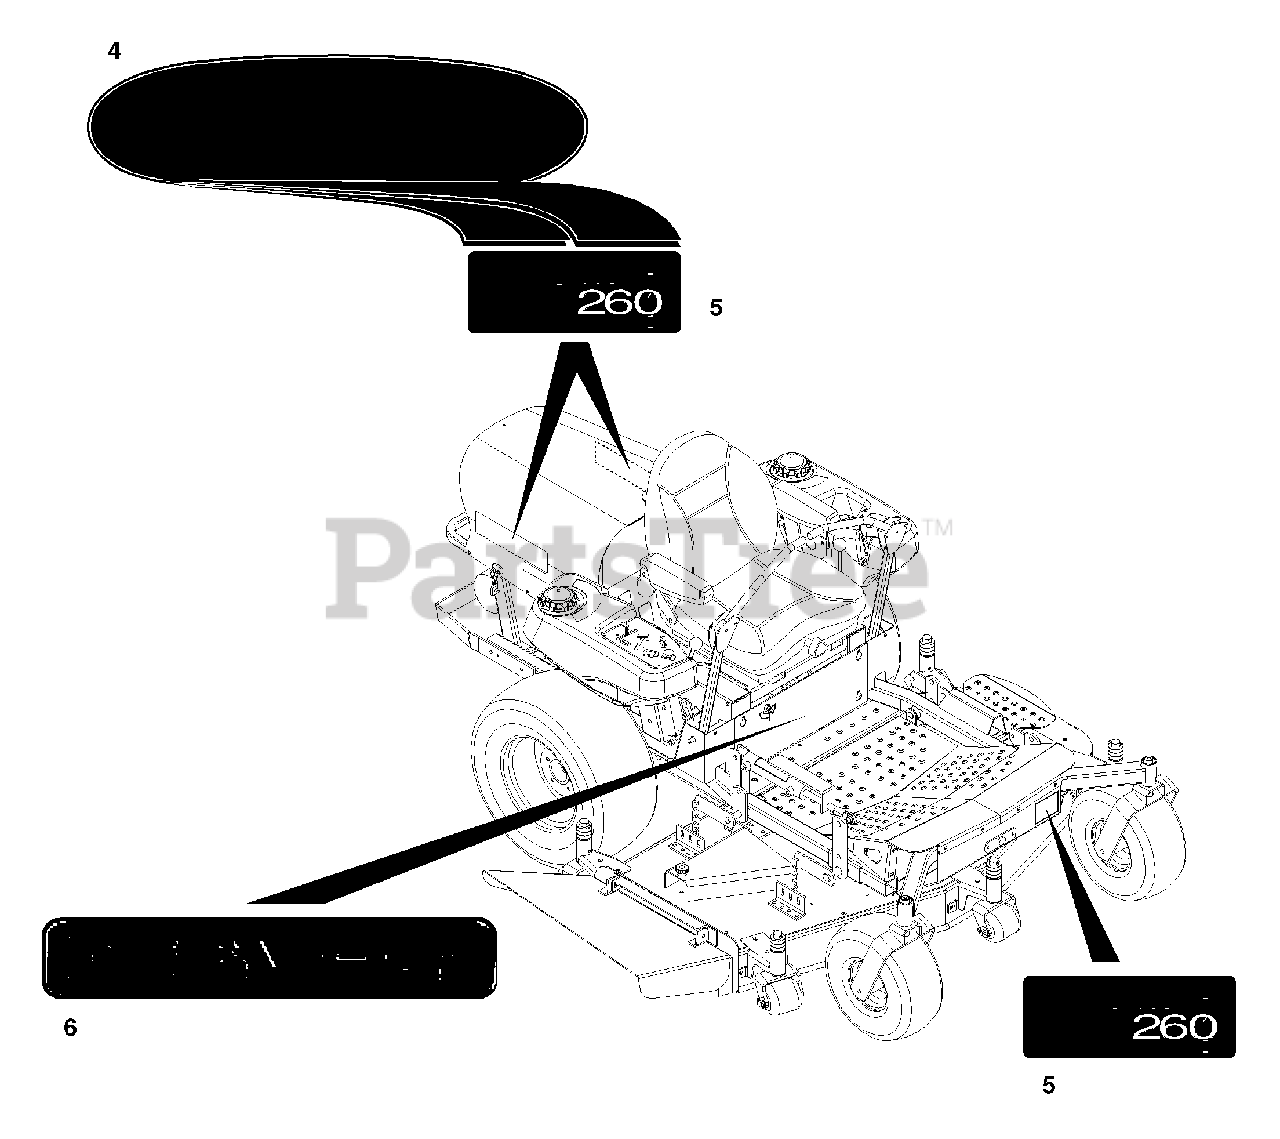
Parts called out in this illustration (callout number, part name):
4	Decal Set Gravely Logo
5	Decal-PM 260Z Logo
5	Decal-PM 250Z Logo
6	Decal-15" Gravely Logo
